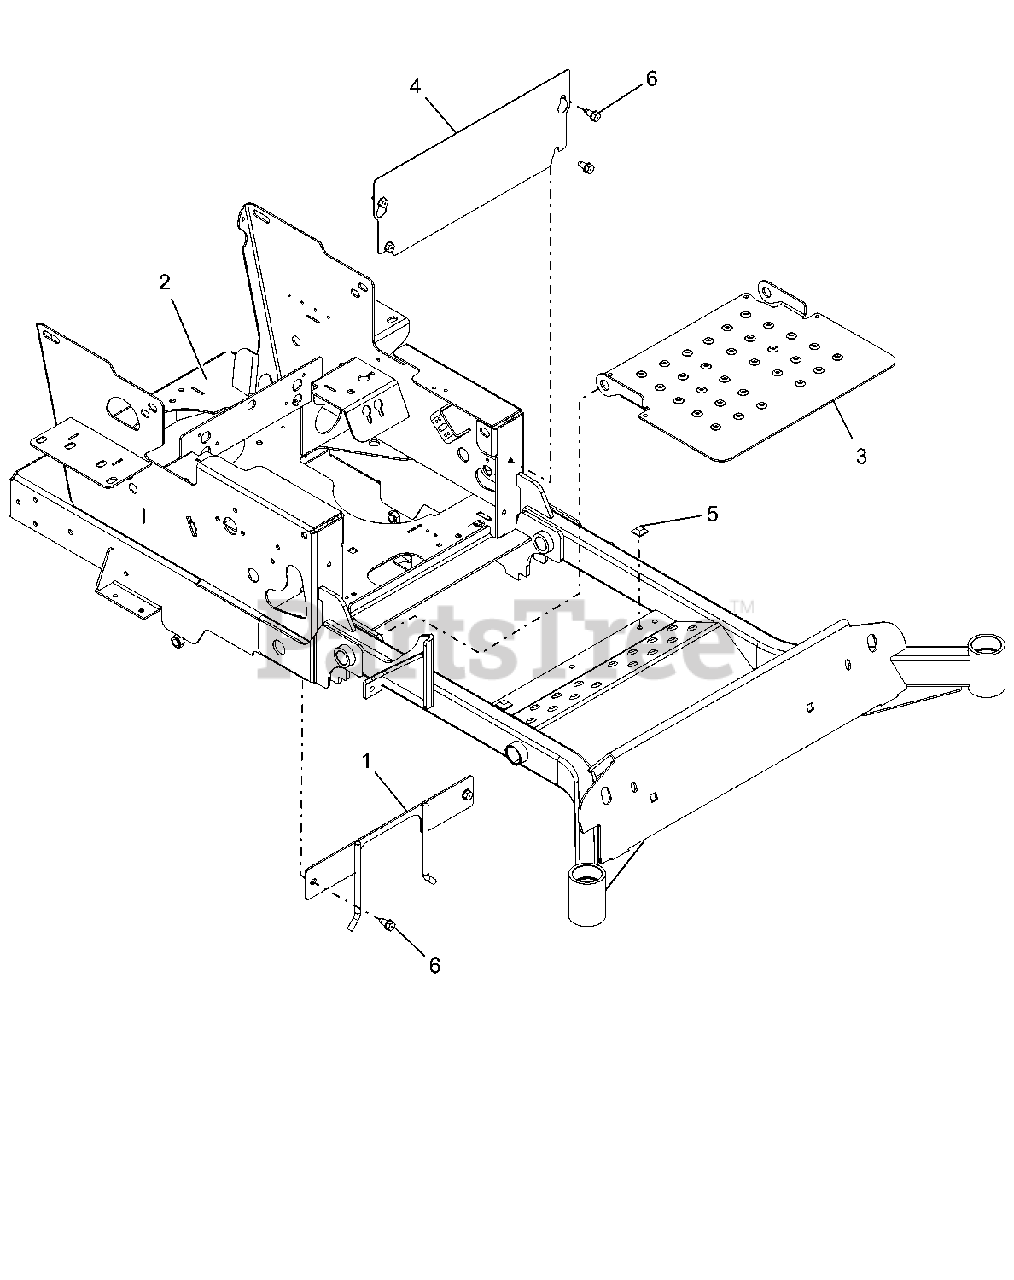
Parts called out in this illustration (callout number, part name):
1	PTO BELT FINGER WLDMT - BLK
2	HD 52-60 FRAME W/SAFETY DECALS
3	INSPECT PNL W/SAFETY DECAL-ORG
4	PLATE, KICK
6	@SCR-TAP .38-16X.75 HWH TR YWZ
